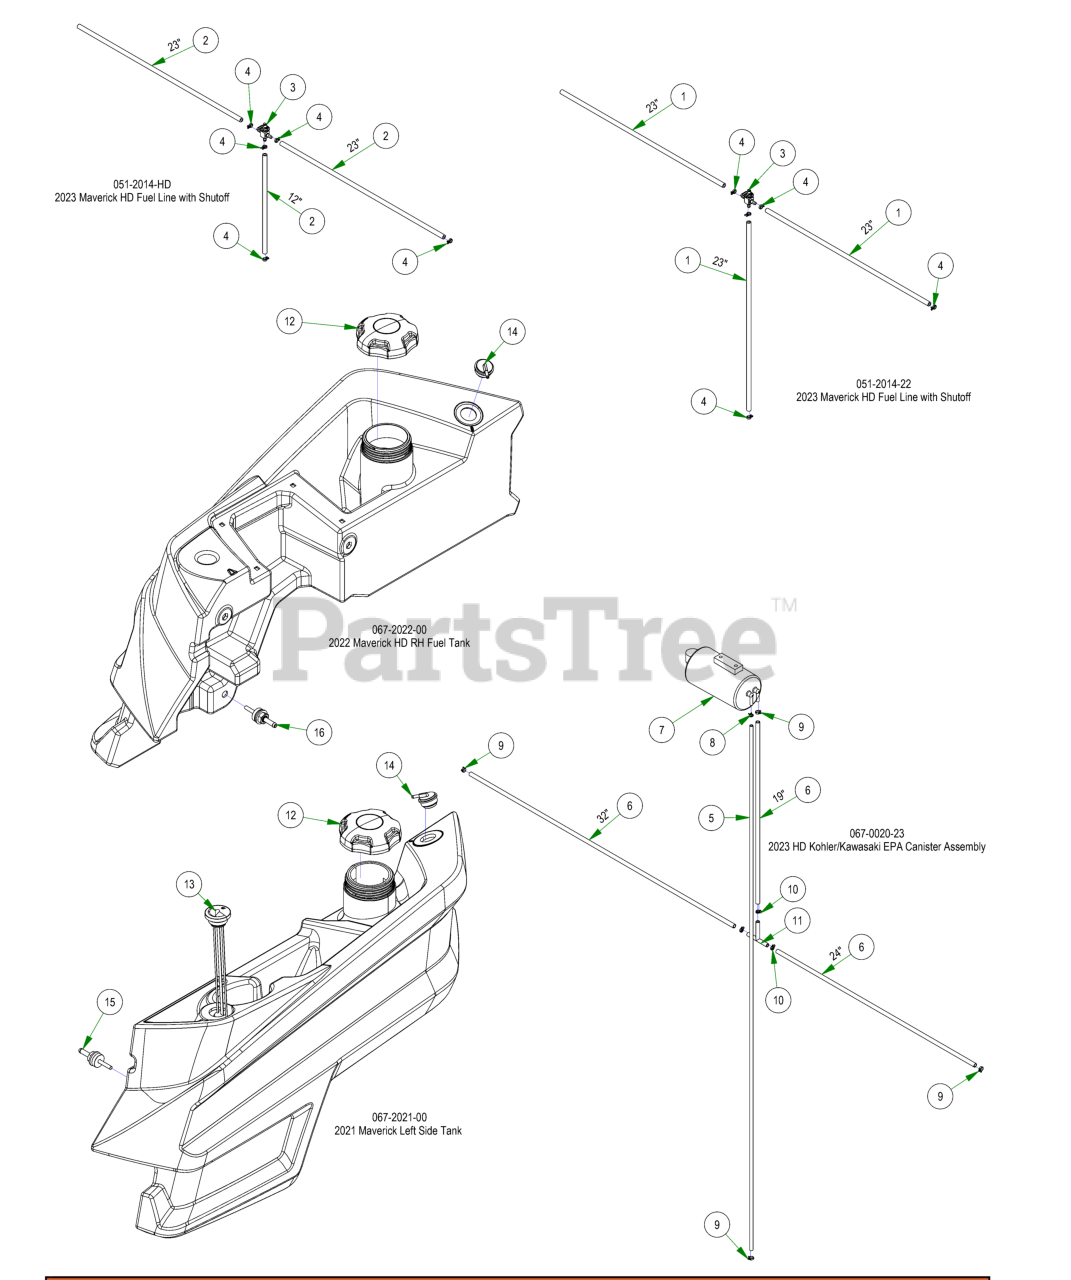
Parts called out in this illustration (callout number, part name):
1	4" 1/4 Fuel Line
2	4" 1/4 Fuel Line
3	3 Way Fuel Shut-Off Valve 1/4x1/4x1/4
4	1/4 Fuel Hose Clamp
5	3/16" Vinyl Tubing, 55" Long
6	1/4" Vinyl Tubing
7	Carbon Canister
8	8.6mm Hose Clamp
9	3/16 Vinyl Clamp
10	Roto DW-6.5ST Z3X
11	fuel line T
13	Fuel Gauge w/Grommet
14	Rollover Valve W/Grommet
15	Fuel Pick-up for 067-2021-00
16	Fuel Pick-up for 067-2022-00
